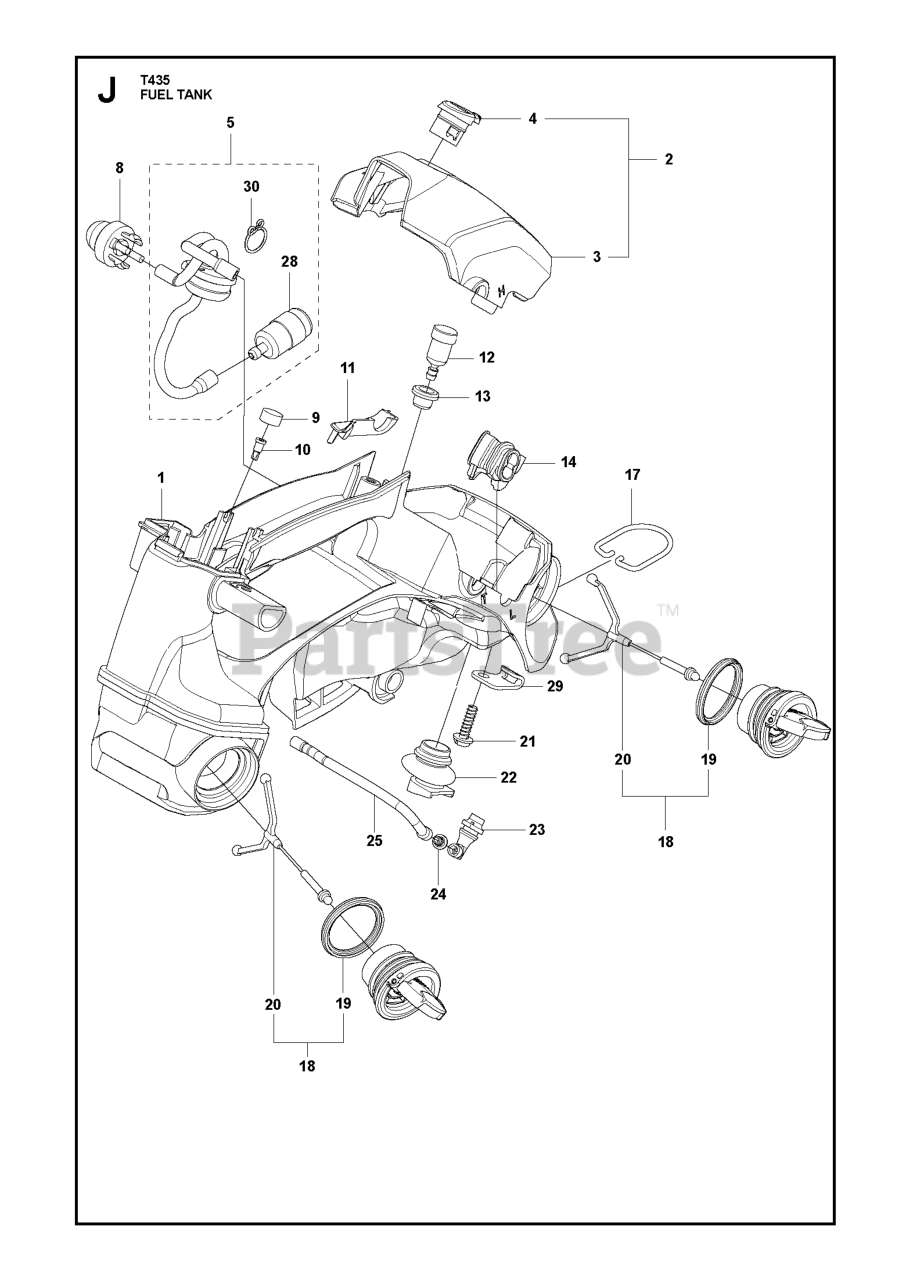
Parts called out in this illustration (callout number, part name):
2	COVER COMP
3	COVER CLEANER
5	FUEL HOSE ASSY
5	FUEL HOSES
8	AIR PURGE BUBBLE
9	BREATHER SEAL
10	AIR CONTROL BREATHER
11	BRACKET KNOB
14	GUIDE CARB
18	TANK CAP ASSY
19	GASKET TANK CAP
21	SCREW (RPLS 267132210)
23	PIPE 848CE085R0
25	FUEL HOSE L=105 ROHS2
29	PLATE EYELET
